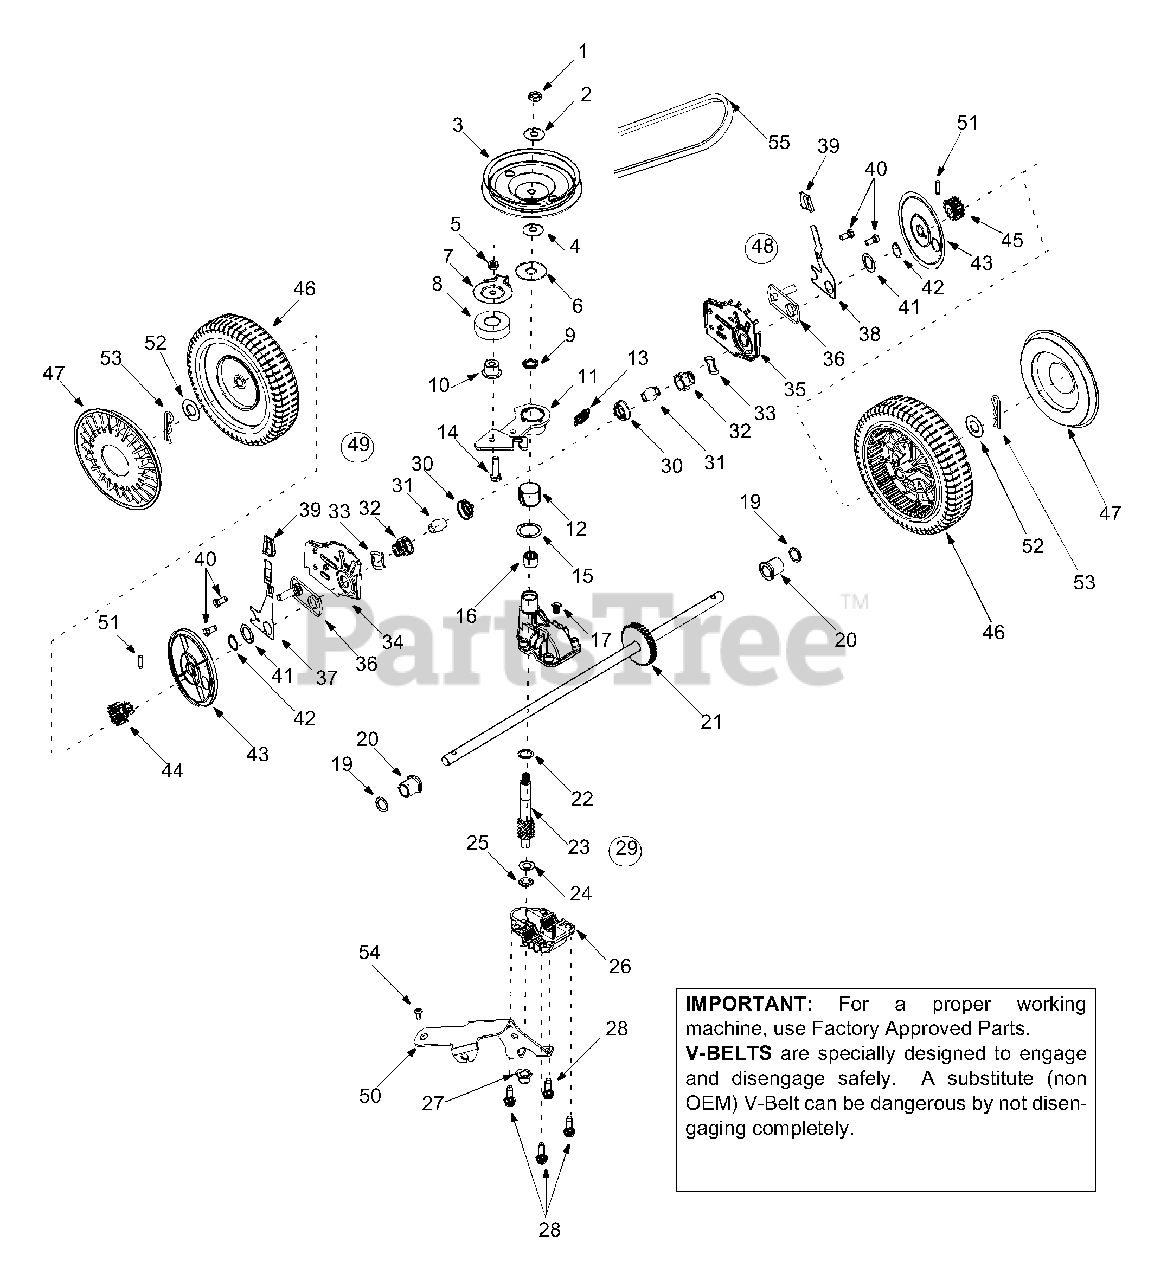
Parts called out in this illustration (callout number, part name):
1	Hex Jam Nut 5/16-24
2	Bell Washer .325 x .930 x .045
3	Pulley, 3.82 x .313 x .68
4	Bell Washer .325 x .930 x .045
5	Lock Nut 1/4-28
6	Flat Washer .442 x 1.38 x .060
8	Ball Bearing
10	Flange Spacer
11	Idler Bracket Assembly
12	Bearing Sleeve
13	Extension Spring
14	Hex Cap Screw 1/4-28 x 1.00
15	Flat Washer .865 x 1.145 x .030
16	Needle Bearing .438 x .625 x .500
17	Plug 1/4 x .437
19	Oil Seal .500 x .687 x .094
20	Flange Bearing
21	Output Shaft
22	Flat Washer .504 x .700 x .030
23	Pinion Shaft 10T
24	Thrust Washer .375 x .70 x .030
25	Thrust Washer .388 x .625 x .062
26	Lower Housing
27	Flange Bearing .378 x .531 x .370
28	Hex Screw w/Washer 1/4-20 x .750
29	Transmission Assembly
30	Bearing Retainer
31	Bearing Sleeve .50 I.D.
32	Bearing Support
33	Wave Washer 1.5 x 1.0 x .029
37	RH Front Lever
38	LH Front Lever
39	Knob
40	Hex Cap Screw 3/8-16 x .75
41	Washer DD 1.5" O.D.
43	Wheel Dust Cap
46	Wheel, 8x2 Black
47	Hubcap: Gray
48	RH Height Adj. Complete
49	LH Height Adj. Complete
50	Cable Idler Bracket
51	Dowel Pin
52	Flat Washer 1/2 x 1.00 x .063
53	Cotter Pin .08 x 1.42
55	Belt
